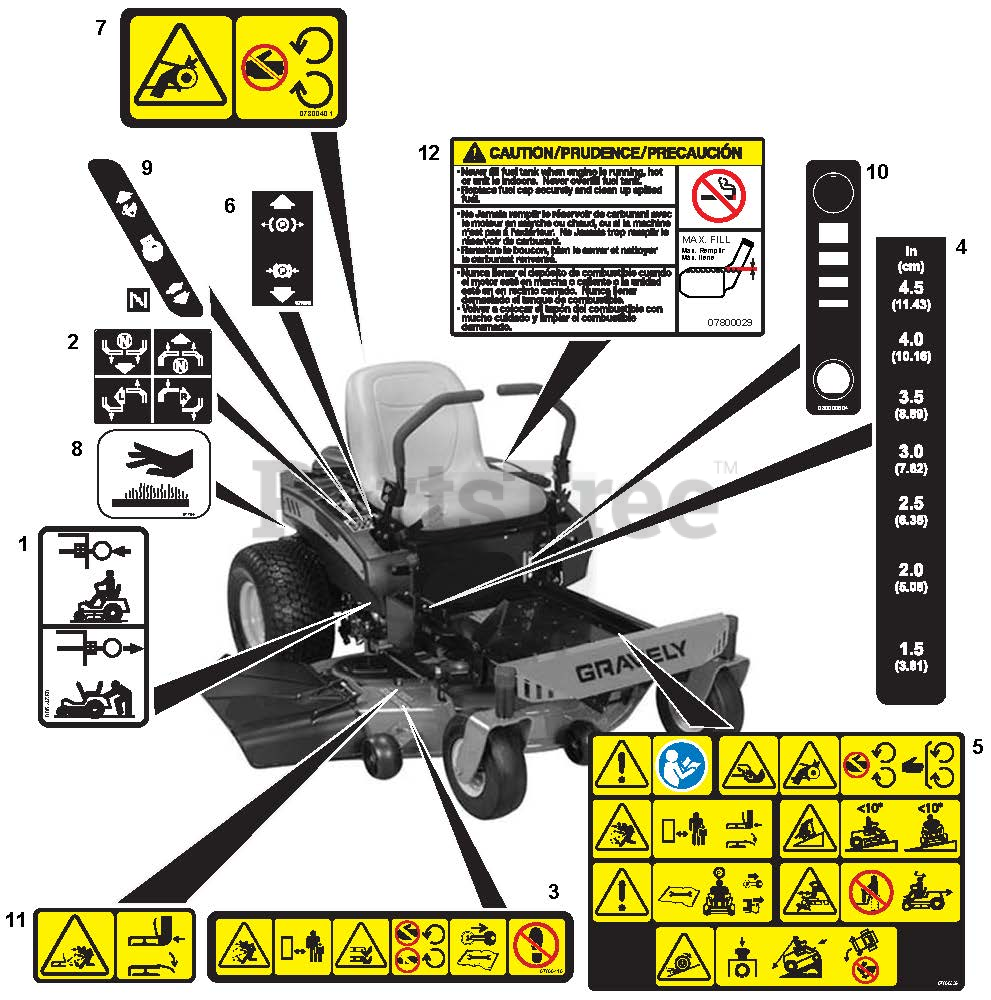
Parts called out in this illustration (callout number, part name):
1	DECAL, TRANSMISSION DISCONNECT
2	DECAL, INSTRUCTIONAL-STEERING
3	DECAL, DECK SAFETY
4	DECAL, HEIGHT OF CUT
5	DECAL, MAIN SAFETY
6	DECAL, PARKING BRAKE LEVER
7	DECAL, SAFETY - GUARDING
8	DECAL, HOT SURFACE
9	DECAL, SPEED CONTROL
10	DECAL, FUEL LEVEL
11	DECAL, SAFETY - DECK GUARDING
12	DECAL-FUEL, WARNING
